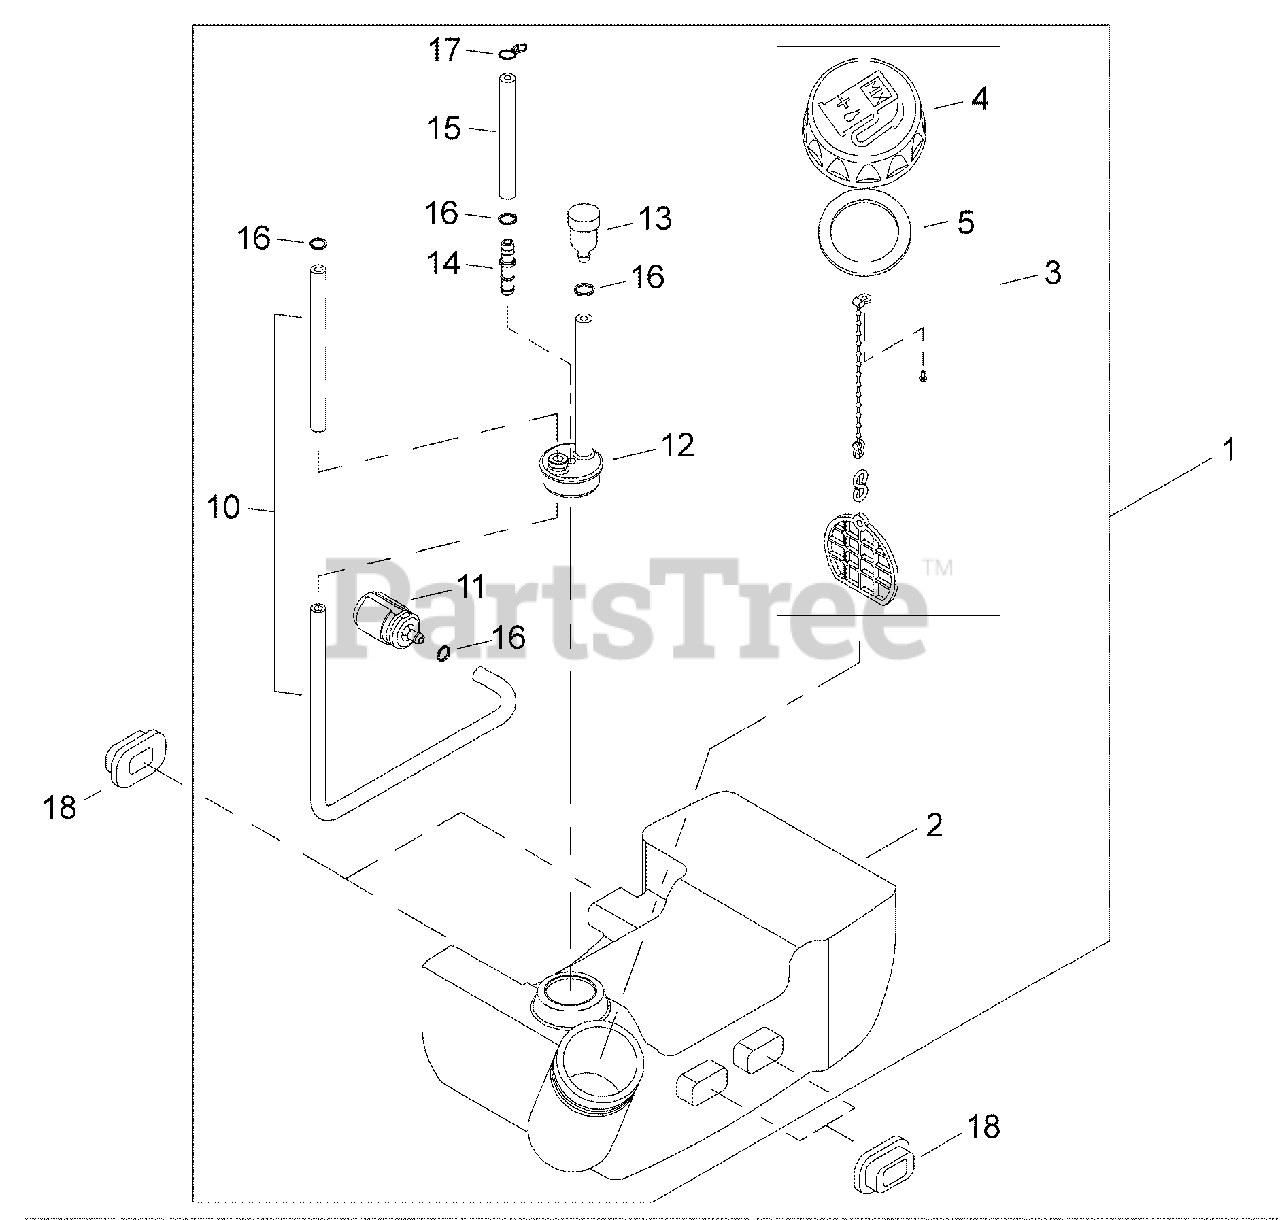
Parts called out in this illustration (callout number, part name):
1	TANK ASSY, FUEL
2	TANK, FUEL
3	CAP ASSY, FUEL
4	CAP, FUEL
5	GASKET, FUEL CAP
10	PIPE, FUEL 3.3×6×160
11	FILTER, FUEL 125-528
12	GROMMET, FUEL W/VENT PIPE
13	VENT ASSY
14	CONNECTOR, PIPE
15	PIPE, FUEL RETURN L= 52.5 MM
16	CLIP Ø6
17	CLIP, SPRING Ø5.2
18	CUSHION, FUEL TANK
